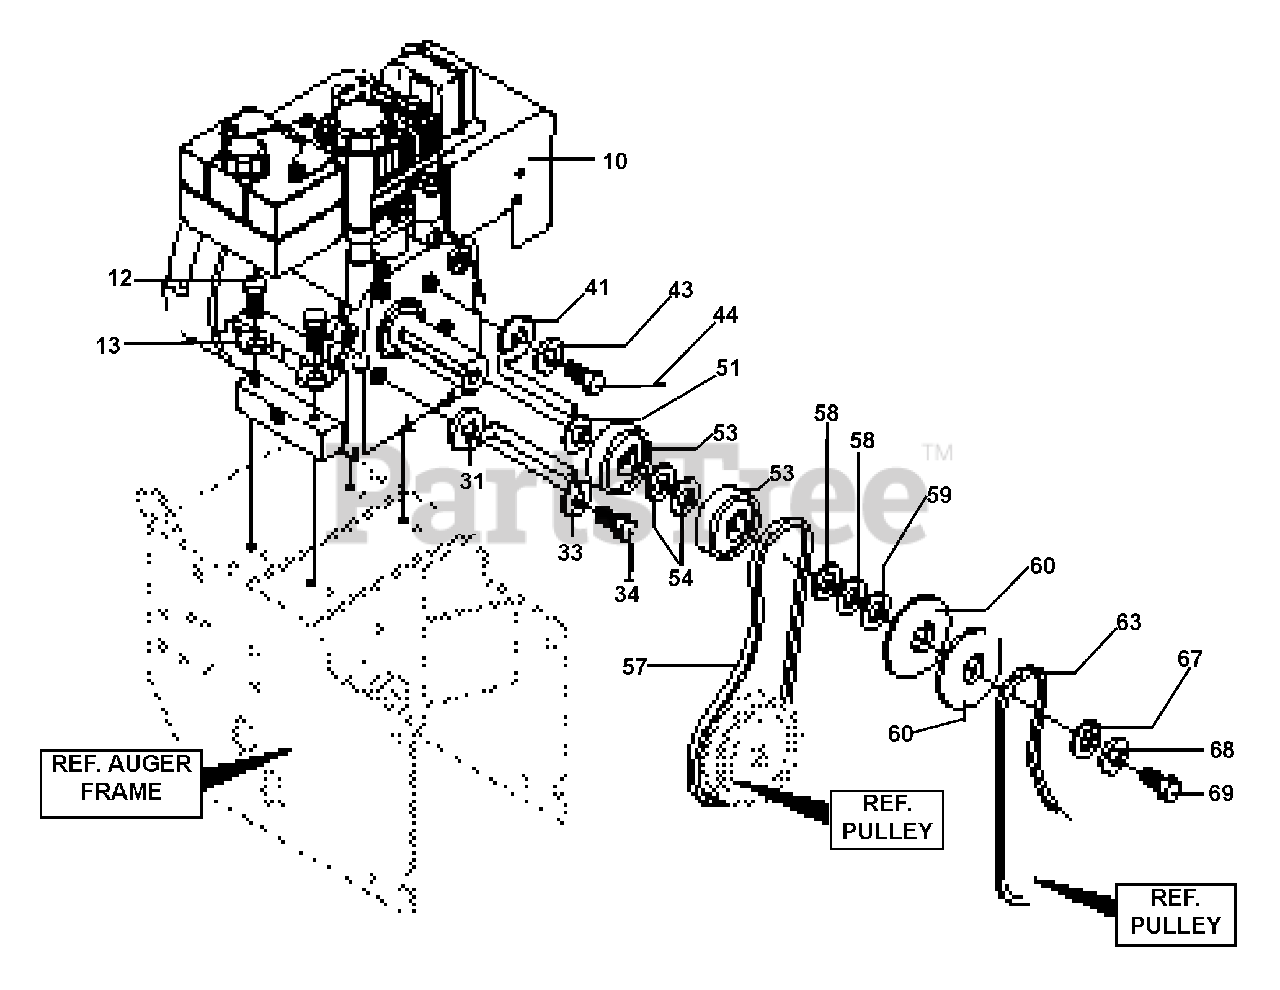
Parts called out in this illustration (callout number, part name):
10	ENGINE 8HP (See Engine Manual)
12	SCREW 5/16-18X1.50
13	WASHER, .328X.60X.09
31	GUIDE, ROD BELT RH
33	WASHER,.328X.60X.09
34	SCREW, 5/16-24X 1.00
41	GUIDE, ROD BELT RH
43	WASHER, .328X.60X.09
44	SCREW, 5/16-24X 1.00
51	WASHER, CRANKSHAFT
53	PULLEY, HALF
54	FLATWASHER.752X.91X.02
57	BELT, V 3L 33.13LG
58	FLATWASHER.765X1.12X.06
59	SPACER, SLEEVE
60	PULLEY, ENG
63	BELT, V 4L 38.1LG
67	WASHER, FLAT
68	WASHER, 393X.68X.10
69	SCREW, 3/8-24X1.00
